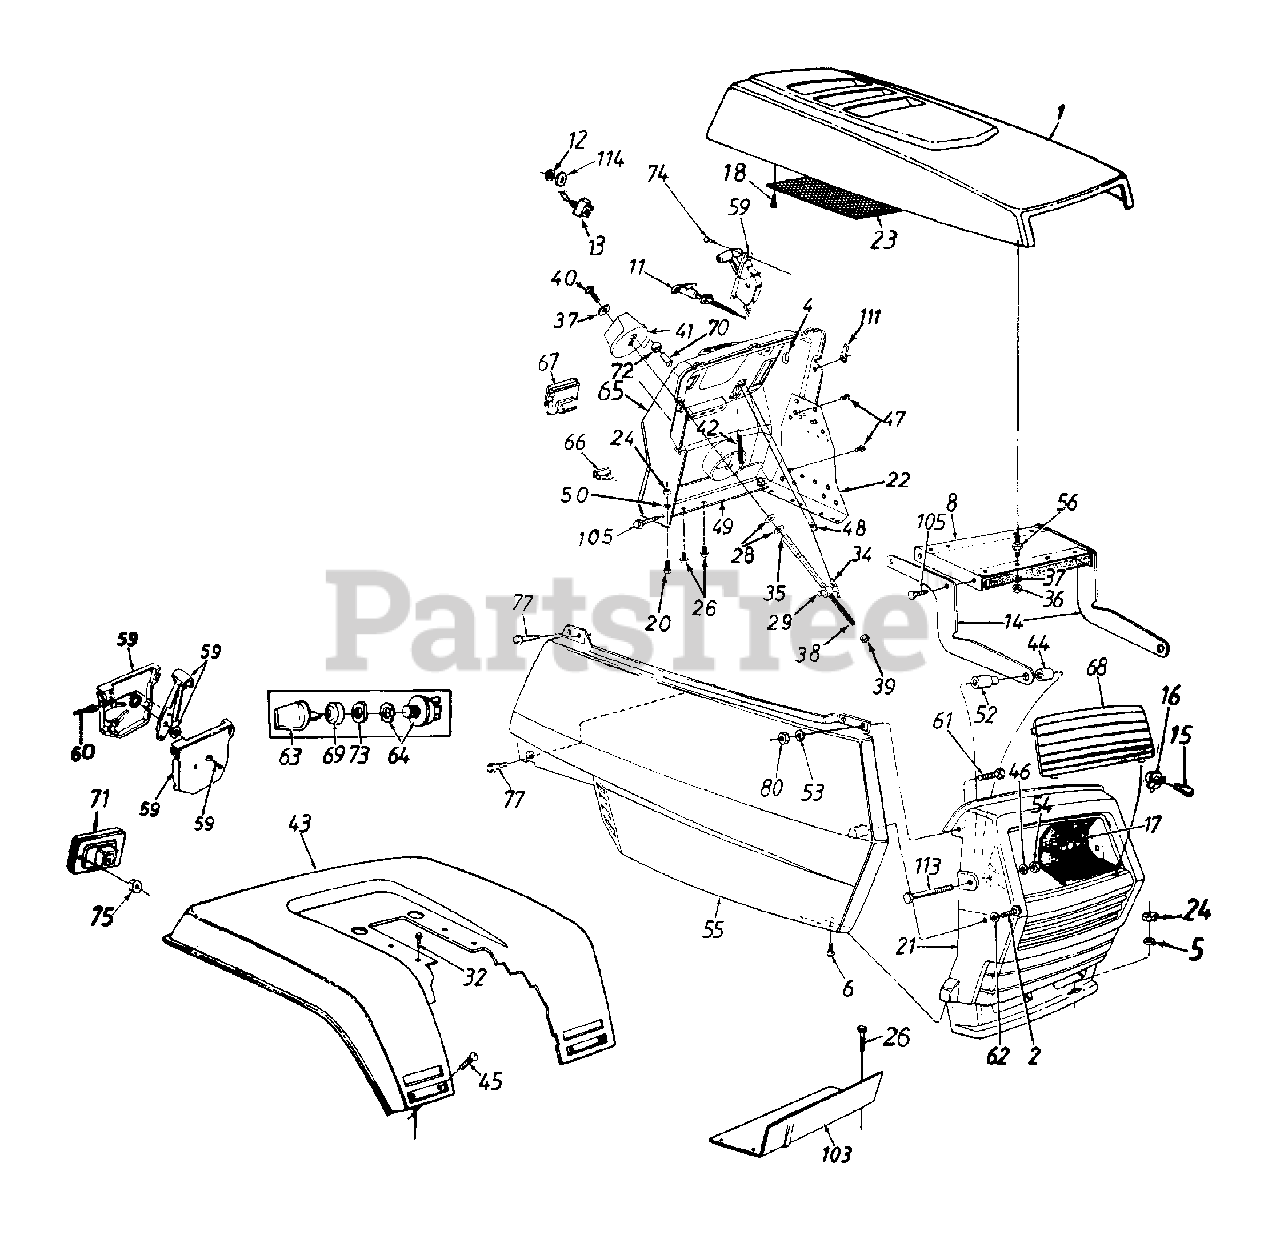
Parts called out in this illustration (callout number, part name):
1	Hood
2	Hex Wash. B-Tap Scr. 1/4 x .62" Lg.
4	Retainer Clip
6	Truss Mach. B-Tap Scr. #10 x .5" Lg.
12	Hex Nut 1/2-27 Thd.
13	Toggle Switch
16	Twist Lock - Lamp Socket
17	Reflector - Headlight
18	Hex Wash. Hd. AB-Tap Scr. #8 x .5" Lg.
20	Hex Bolt 5/16-18 x .75" Lg.
21	Grille
24	Hex Sems Nut 5/16-18 Thd.
26	Hex Wash. SF Tap Scr. 5/16-18 x .5" Lg.
28	Fl-Wash. 3/8" I.D. x .875" O.D.
29	Adj. Ferrule 3/8-8 Thd.
34	Hairpin Clip
35	"E"-Ring .375" Dia.
36	Hex Nut 1/4-20 Thd. (Gr. 5)
37	Bell-Wash. .265" I.D. x .75"
38	Adjustment Rod
39	Hex Nut 3/8-8 Twin Thd.
40	Hex Bolt 1/4-20 x .75" Lg.
41	Plastic Knob
42	Ext. Spring 3.21" Lg.
45	Pan Screw 1/4-20 x .50" Lg.
46	Fl-Wash. .328" I.D. x .68" O.D.
47	Hex Wash. Hd. Scr. 1/4-20 x .5" Lg.
48	Indicator Strip
52	Shld. Spacer .33" I.D.
53	Fl-Wash. .281" I.D. x .5" O.D.
54	Hex Cent. L-Nut 5/16-18 Thd.
55	Side Cover - R.H.
56	Double Ended Stud 1/4-20 Thd.
59	Throttle Control Box Ass'y.
60	Throttle Control Wire 22" Lg.
61	Hex Bolt 1/4-20 x .62" Lg.
62	Fl-Wash. .281" I.D. x .73" O.D.
64	Ignition Switch
65	Dash Panel
66	Light Switch
67	Ammeter
68	Lens
69	Ignition Switch Cap
70	Ball Plunger
73	Ignition Switch Nut
74	Truss Mach. AB-Tap Scr. #10 x .5" Lg.
75	Hex Nut 10-32
77	Hex Wash. Hd. Tap Scr. 1/4 x .75" Lg.
80	Hex L-Nut 1/4-20 Thd.
111	Speed Nut 1/4-20 Thd.
113	Hex Bolt 5/16-18 x 2.75"
114	Lock Washer 1/2: Internal tooth
